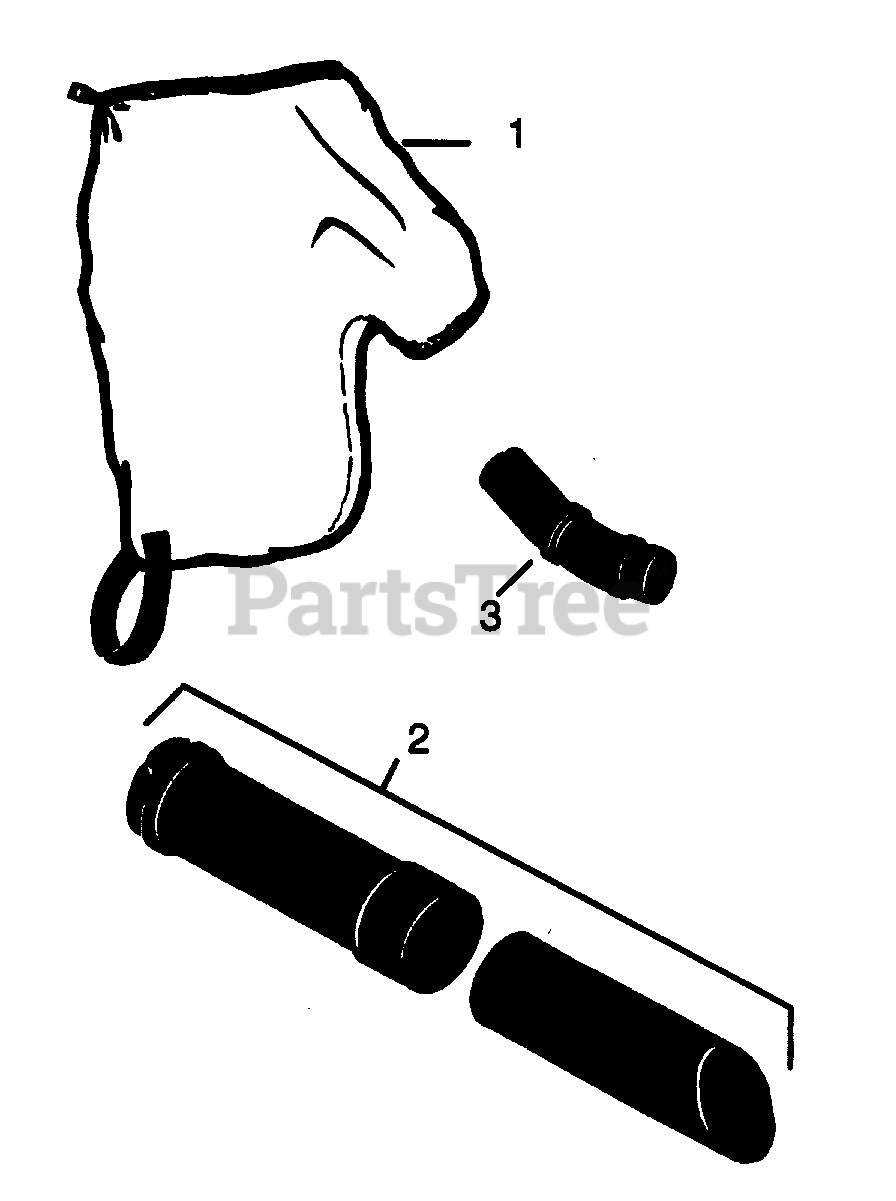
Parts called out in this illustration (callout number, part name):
1	Collection Bag
2	Vacuum Tubes
3	Vacuum Elbow
